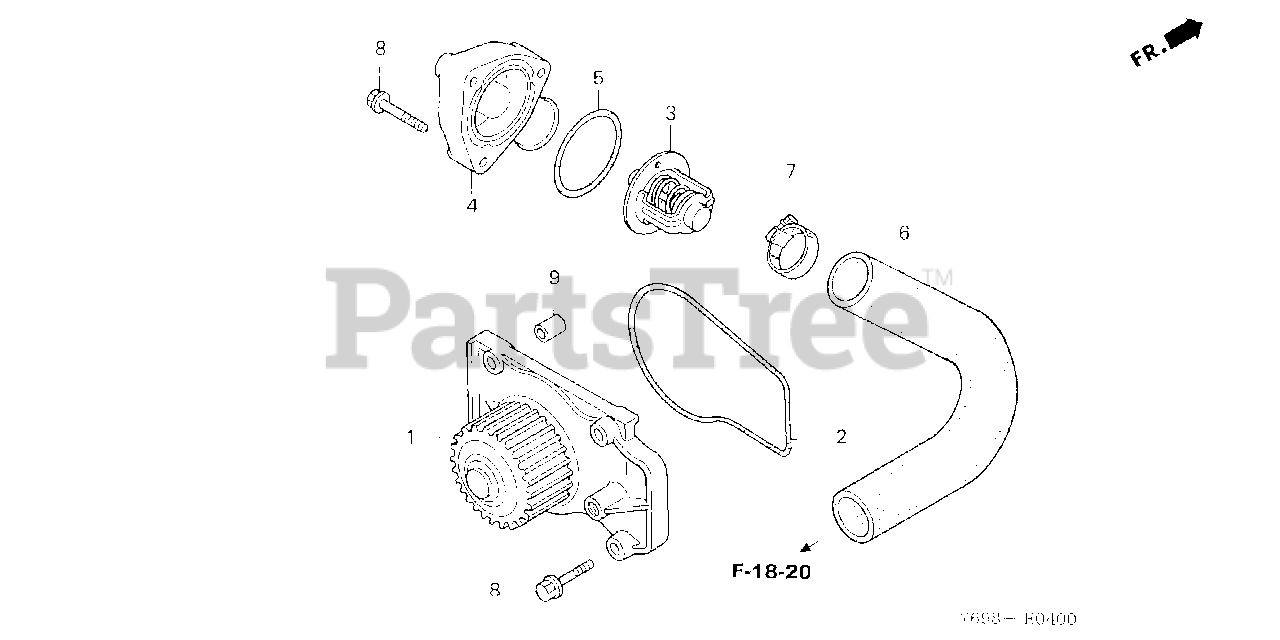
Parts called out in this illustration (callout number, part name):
1	WATER PUMP
2	O-RING, WATER PUMP
3	THERMOSTAT
4	COVER, THERMOSTAT
5	O-RING, THERMOSTAT COVER
6	HOSE B, WATER (LOWER)
7	BAND, WATER HOSE
8	BOLT, FLANGE (6X32)
9	PIN A, DOWEL (8X14)
